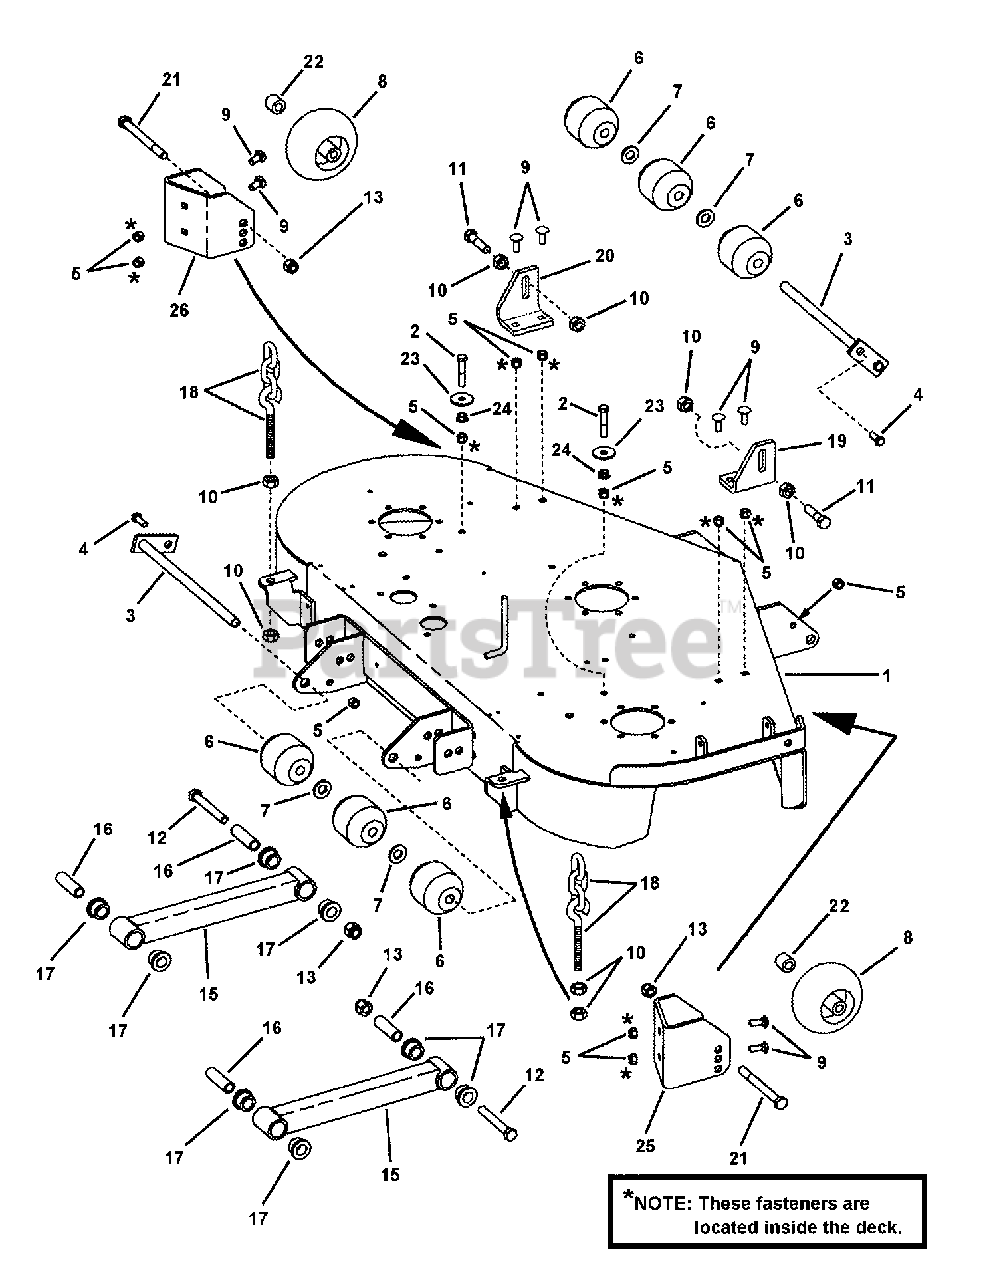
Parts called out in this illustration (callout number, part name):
1	WELDMENT, 52" Deck
2	BOLT, 3/8-16 X 2, GD5, CZ
3	WELDMENT Pivot Pin
4	BOLT, 3/8-16 X 1" GD5 CZ
5	NUT, 3/8-16 HEX NYLON LOCK
6	ROLLER Low Density Polyethylene
7	WASHER, 5/8" Flat SAE
8	GAUGE WHEEL, Polyethylene
9	BOLT, 3/8-16 x 1" Square Neck Carriage, GR 5
10	NUT, 1/2-13 HEX
11	SCREW, 1/2-13 x 2" Hex Head Cap, GR 5
12	BOLT, 1/2-13 x 3-3/4" Hex Head Cap, GR 5
13	NUT, 1/2-13 HEX NYLON LOCK
14	ASSEMBLY, Pusher Bar (Includes items 15-17)
15	WELDMENT, Pusher Bar
16	SLEEVE - Suspension
17	BUSHING - Suspension
18	ASSEMBLY, Chain & Eyebolt (see Front Frame Assy page)
19	BRACKET, Front Deck Hanger R. H.
20	BRACKET, Front Deck Hanger L. H.
21	BOLT, 1/2-13 X 5 GD5 YZ
22	SPACER, Gauge Wheel
23	WASHER, .406 x 1.50 x .120 Flat
24	NUT, 3/8-16 HEX SERRATED FLANGE
25	WHEEL BRACKET Front Right
26	WHEEL BRACKET Front Left
